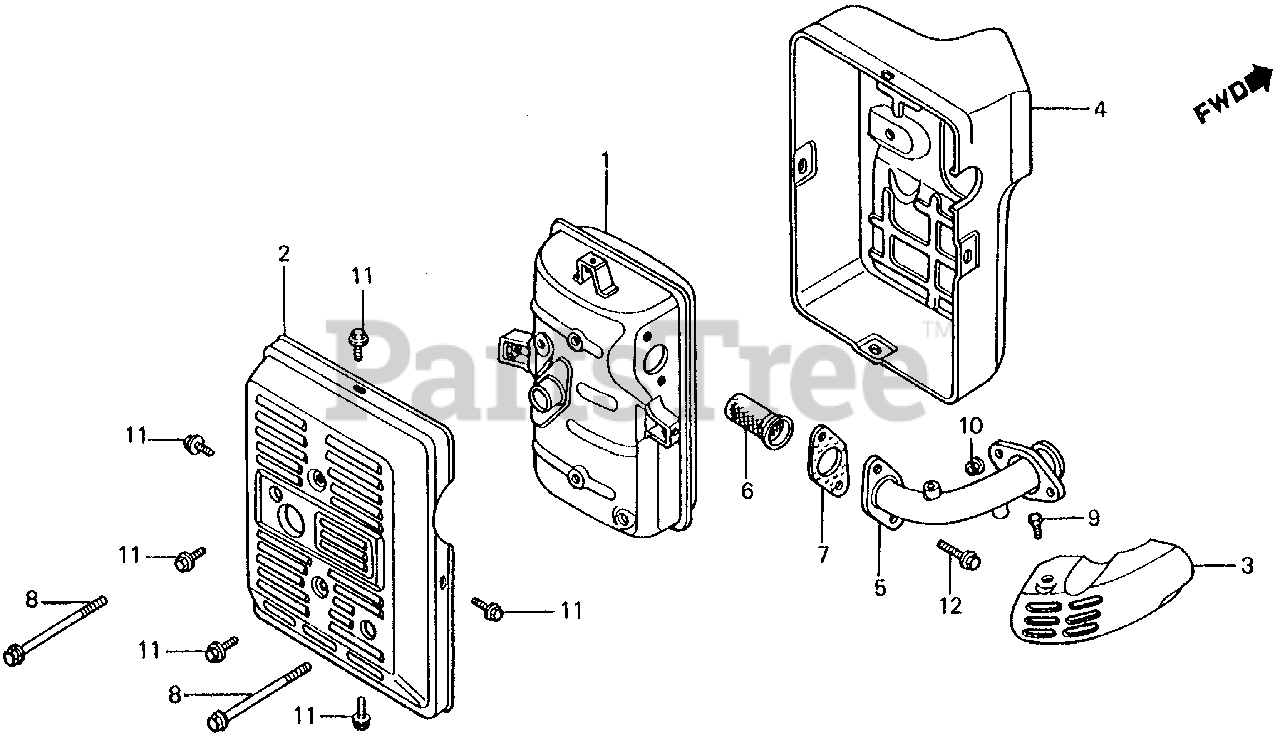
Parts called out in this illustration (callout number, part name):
1	MUFFLER (NOT AVAILABLE)
2	PROTECTOR, MUFFLER (OUTER)
3	PROTECTOR, EX. PIPE
4	PROTECTOR, MUFFLER (INNER)
6	ARRESTER, SPARK
7	GASKET, MUFFLER
8	BOLT, FLANGE (6X103)
9	BOLT, HEX. (6X8)
10	NUT, FLANGE (8MM)
11	BOLT, FLANGE (6X10)
12	BOLT, FLANGE (8X20)
